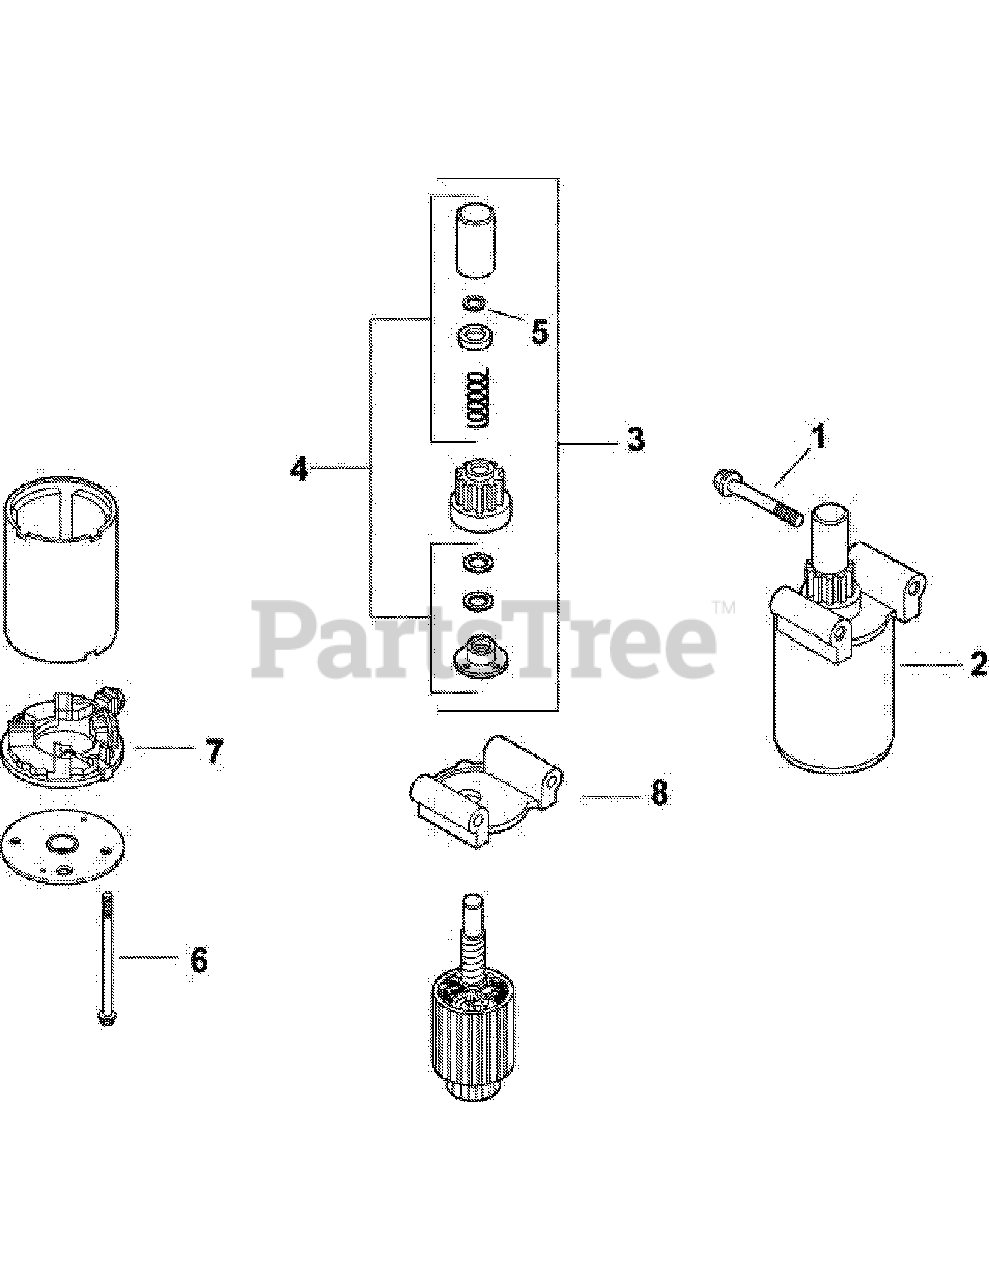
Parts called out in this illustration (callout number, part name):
1	SCREW, FLG M8X1.25X80 - USE M-851080-S
2	STARTER ASSEMBLY
3	KIT, DRIVE
4	KIT, DRIVE PARTS
7	COMMUTATOR, END CAP
8	CAP, DRIVE END
